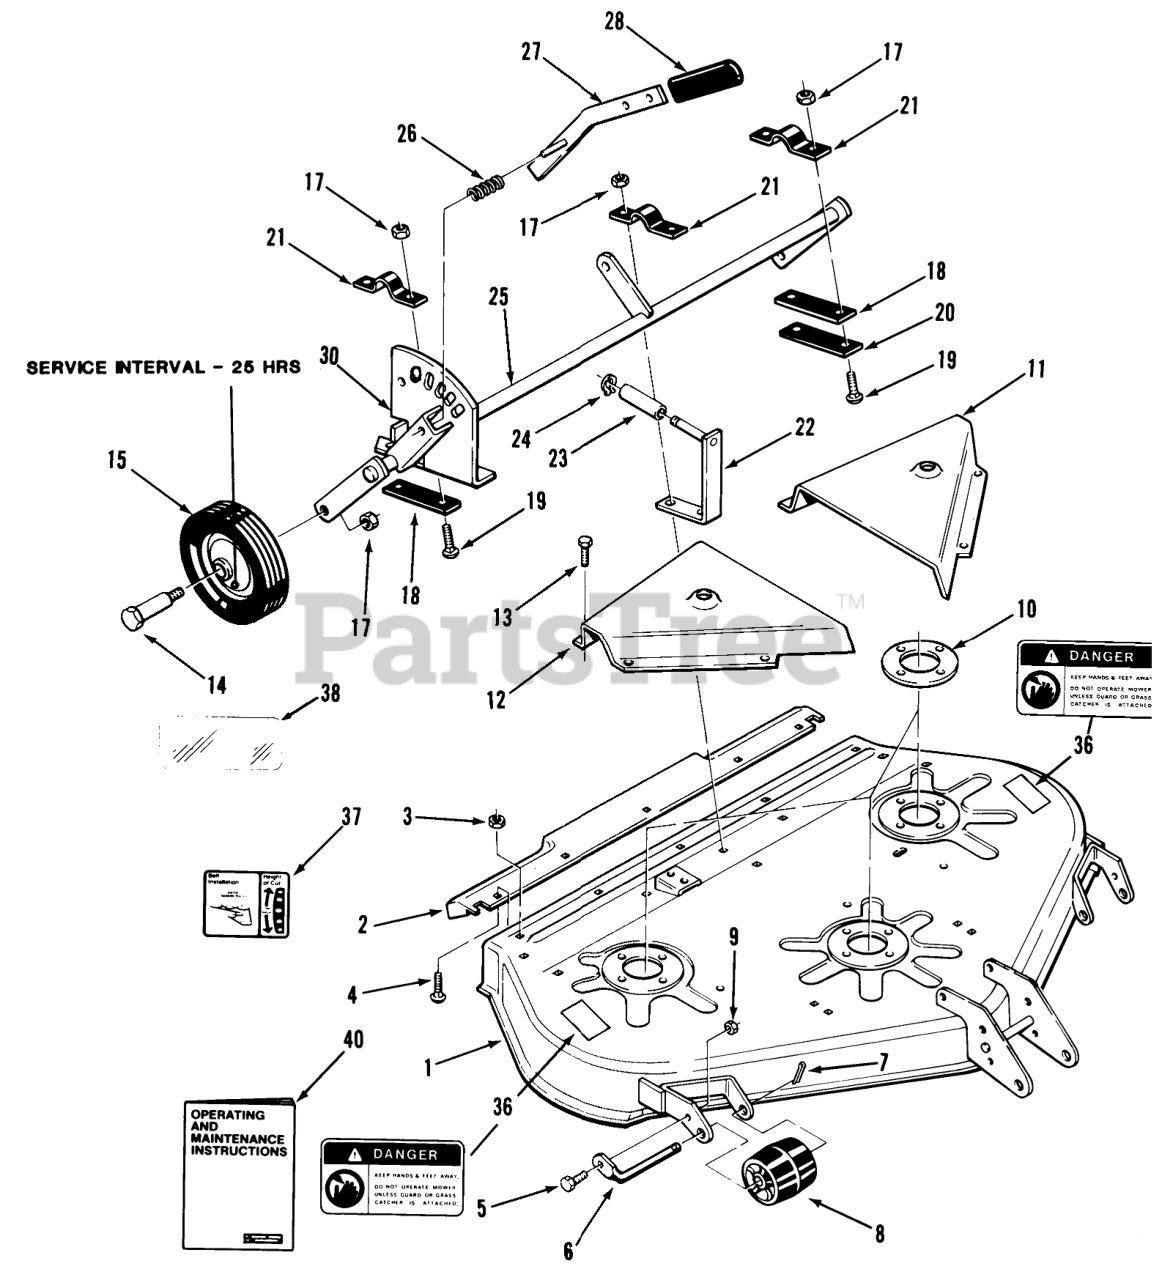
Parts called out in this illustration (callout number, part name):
1	ASSY-42"MOWER DEC R
2	EXTENSION R
3	Nut
4	Bolt
5	Bolt
6	ROLLER-SHAFT
7	Cotter Pin
8	Roller
9	Nut
10	PLATE-SPINDLE
11	Belt Cover LH
12	Belt Cover RH
13	Bolt
14	BOLT-SHOULDER
15	WHEEL
17	NUT
18	STRAP 1/16 B
19	Bolt
20	Bar
22	ASSY-GUIDE BRKT 4 R
23	SPACER
24	Snap Ring
25	Gage Wheel Support
26	SPRING-COMPRESSION
27	Lever
30	Quadrant
36	Danger Decal
37	DECAL-HEIGHT BELT
38	DECAL-OVERLAY
40	Owner-s & Maintenance Instructions
